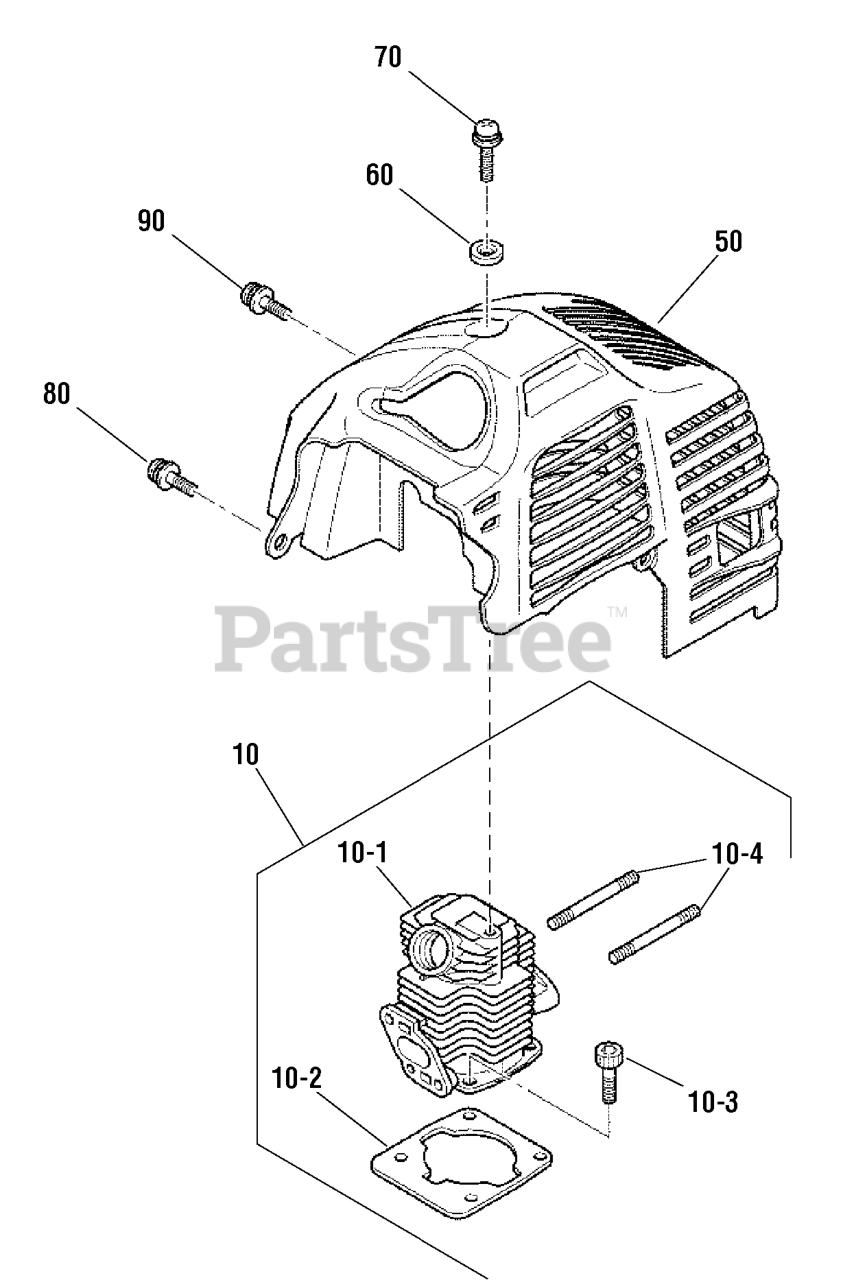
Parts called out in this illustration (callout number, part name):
10	CYLINDER ASSEMBLY
10-1	CYLINDER
10-2	GASKET, Cylinder
10-3	BOLT
10-4	BOLT, Stud
50	COVER, Top
60	SCREW & WASHER
70	SCREW & WASHER
80	SCREW & WASHER
90	WASHER
